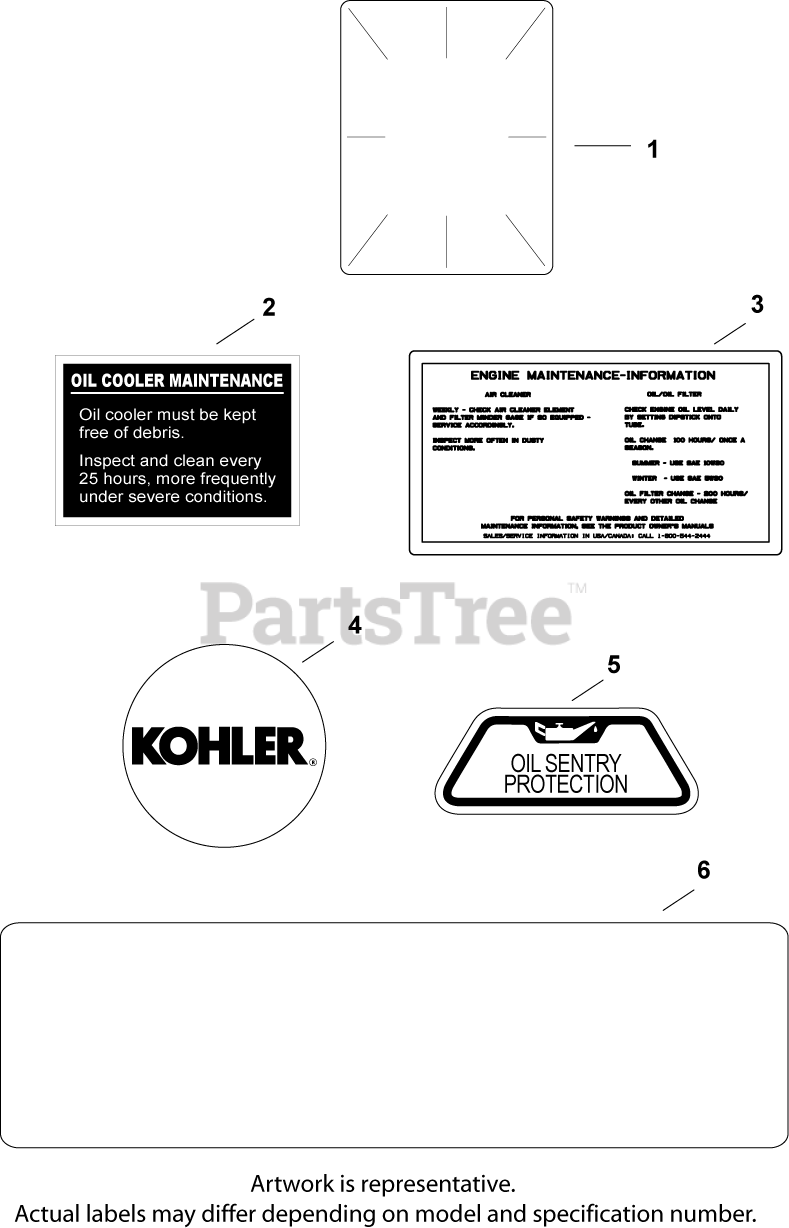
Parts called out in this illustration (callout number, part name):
1	DECAL, CLEAR LAMINATE USE 25 113 70-S
2	DECAL, OIL COOLER - (#DSC)
3	DECAL, AIR CLEANER - (#DSC)
4	LABEL, (ROUND KOHLER GOLD)-USE 24 113 18
5	DECAL, OIL SENTRY - (#DSC)
6	DECAL, 25 HP
